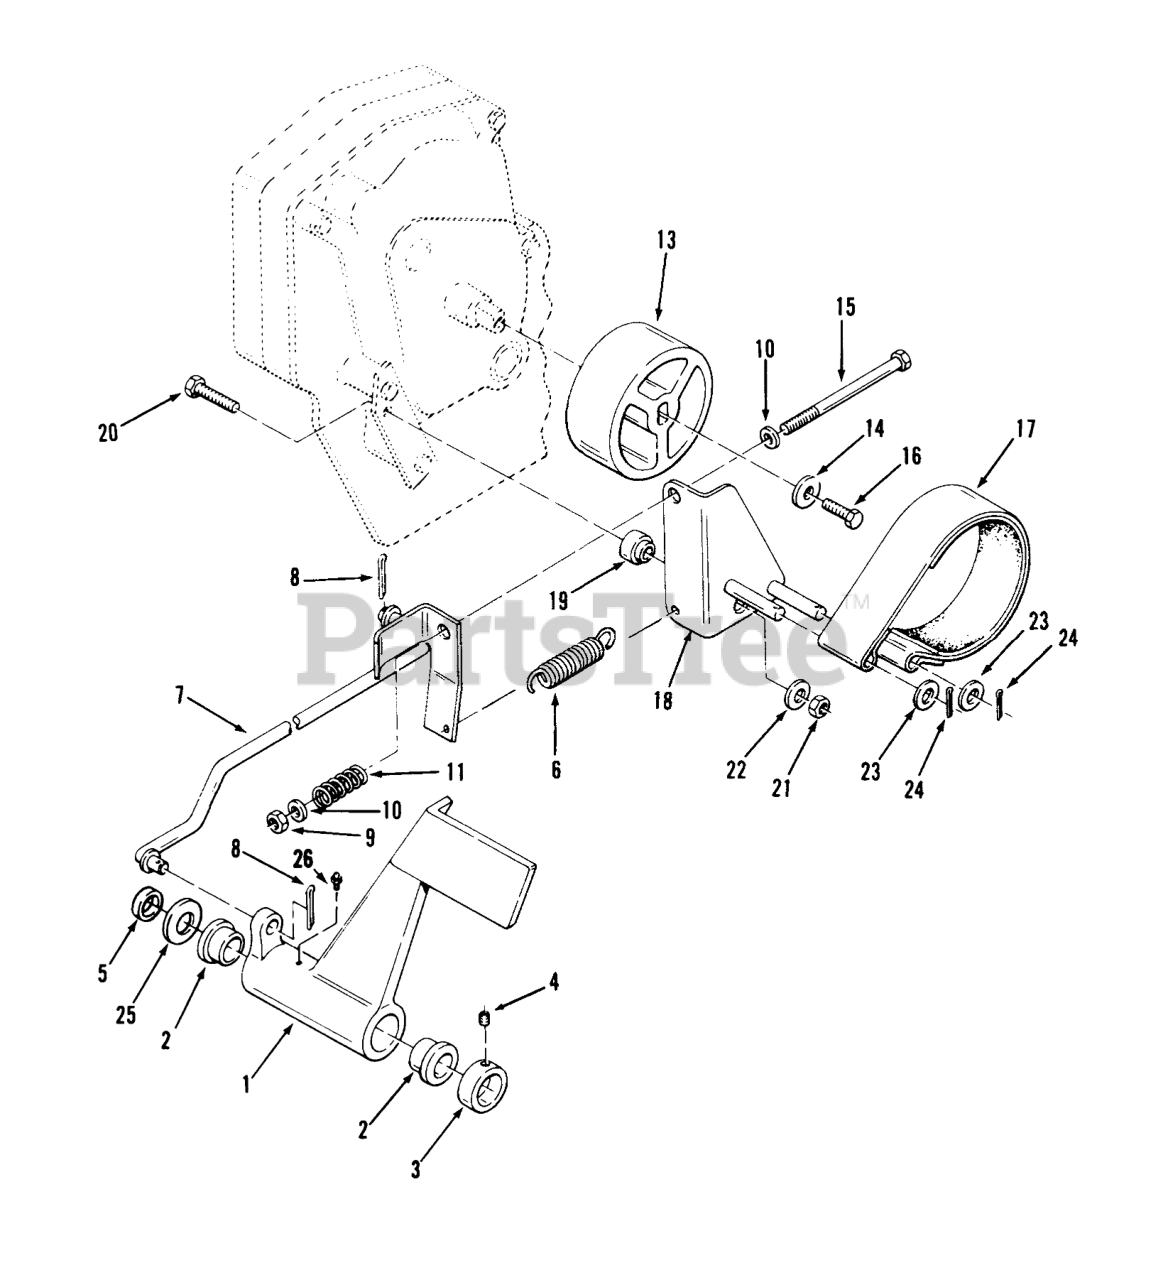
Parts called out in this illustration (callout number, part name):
1	Pedal-Brake
2	BUSHING
3	Collar
4	SCREW-HSH
5	SPACER
6	SPRING
7	ASY BRAK RD WAR
8	PIN-COTTER
9	NUT-LOCK, NI
10	WASHER-FLAT
11	SPRING-COMPRESSION
13	DRUM-BRAKE
14	WASHER
15	SCREW-HH
16	SCREW-HH, LOCK
17	ASSY-BRAKE BAND
18	BRACKET-BRAKEB
19	BUSHING-BRAKE PIVOT
20	SCREW-HH
21	NUT-LOCK, NI
22	WASHER-FLAT
23	WASHER-FLAT
24	PIN-COTTER
25	WASHER
26	Zerk
